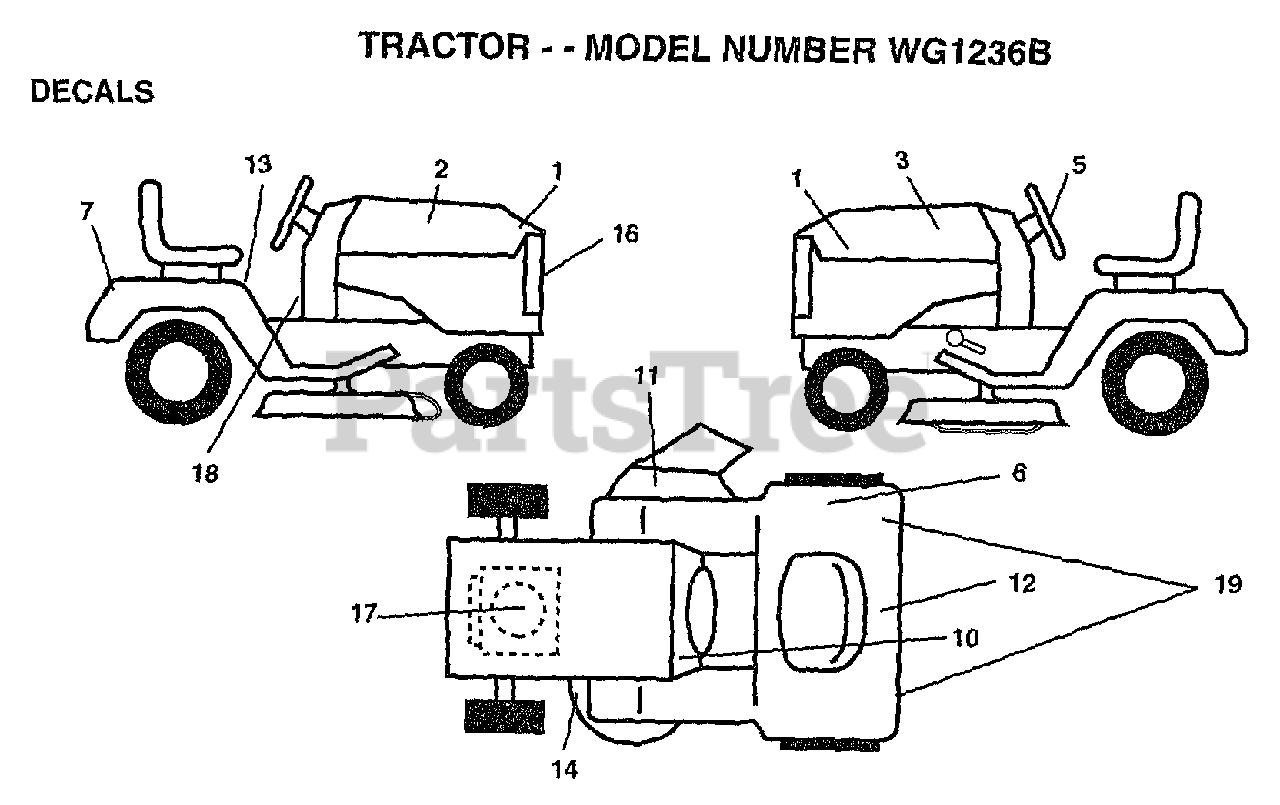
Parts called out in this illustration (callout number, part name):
1	DECAL PNL SIDE RH
2	DECAL.HD.RH.B&S
3	DECAL.HD.LH.B&S
5	DECAL.WHL.STRG.
7	DECAL.FENDER
10	DECAL.OP.INST.SYM
11	DECAL.DANGER.CUTF
12	DECAL.BATRY.3-3908
13	DECAL.READ.O.MANU
14	DECAL.V.BELT
